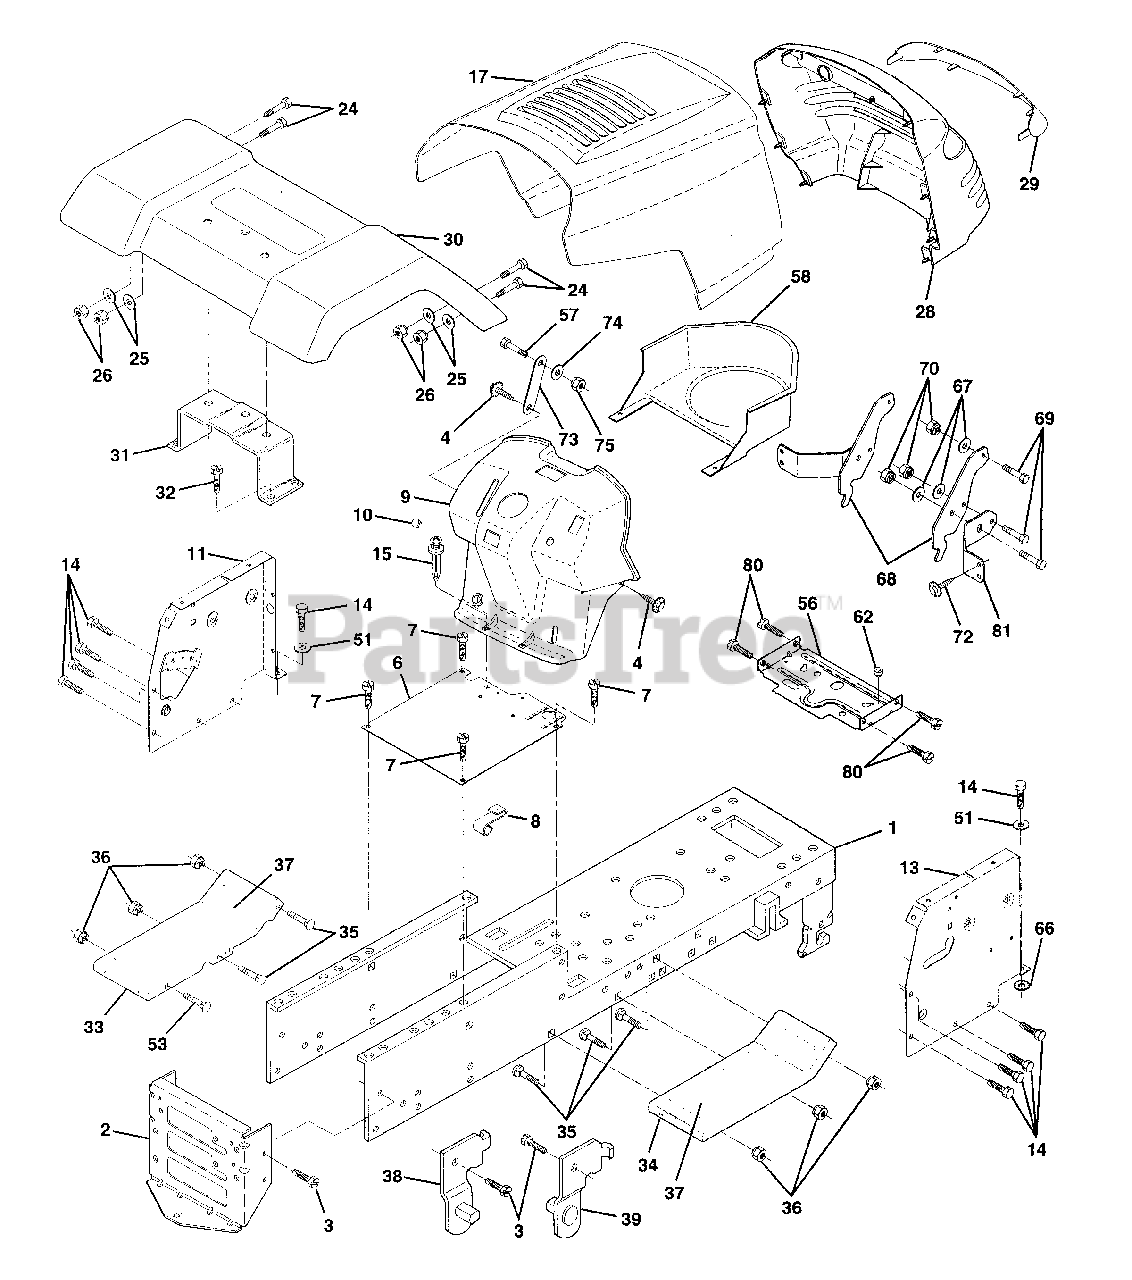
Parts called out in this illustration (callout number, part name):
1	Chassis Weldment 11 ga
2	Drawbar, Stretch
3	Screw Thdrol 3/8-16x3/4 Ty-tt
4	Screw Hexwsh. Thdrol 1/4-20 x 3/4
6	Saddle LT Fender Shift
7	Screw Thdrol 3/8-16x3/4 Ty-tt
8	Clip Line Fuel 13/32 Mtg Hole
9	Dash Private Label
10	Plug Button
11	Panel Pnt Dash Lh
13	Panel Dash Rh Weldment
14	Screw Thdrol 3/8-16x1/2 Ty-tt
15	Rivet Push
17	Hood Paint Steel Private Label
24	Bolt Fin Hex 3/8-16unc X1
25	Washer 13/32 X 13/16 X 12 Ga
26	Nut Lock 3/8-16 Unc
28	Grille Private Label
29	Lens Grille Private Label
30	Fender Pnt
31	Bracket Pnt Fender
32	Screw Thdrol 3/8-16x3/4 Ty-tt
33	Footrest Pnt Lh
34	Footrest Pnt Rh
35	Bolt Rdhd Sht Sqnk 3/8-16 X 3/4
36	Nut Crownlock 3/8-16 Unc
37	Pad Footrest
38	Bracket, Asm. Pivot, L.H., Mower Rear
39	Bracket, Asm. Pivot, R.H., Mower Rear
51	Washer 13/32 x 3/4 x 16 Ga.
53	Bolt Carriage 3/8-16 x 1
56	Support Battery
57	Screw Hex 1/4-20 x 3/4
58	Air Duct P/L
66	Washer Lock Ext. Tooth 3/8
67	Washer 9/32 x 7/8 x 16 Ga.
68	Hinge Pickoff Hood
69	Bolt Hex Hd 1/4-20
70	Nut, Crownlock 1/4-20
72	Screw Lock Spider #8 x 7/8
74	Washer 9/32 x 7/8 x 16 Ga.
75	Nut Lock Hex W/Ins 1/4-20
80	Screw Thdrol 5/16-18 X3/4
81	Bracket, Grill
